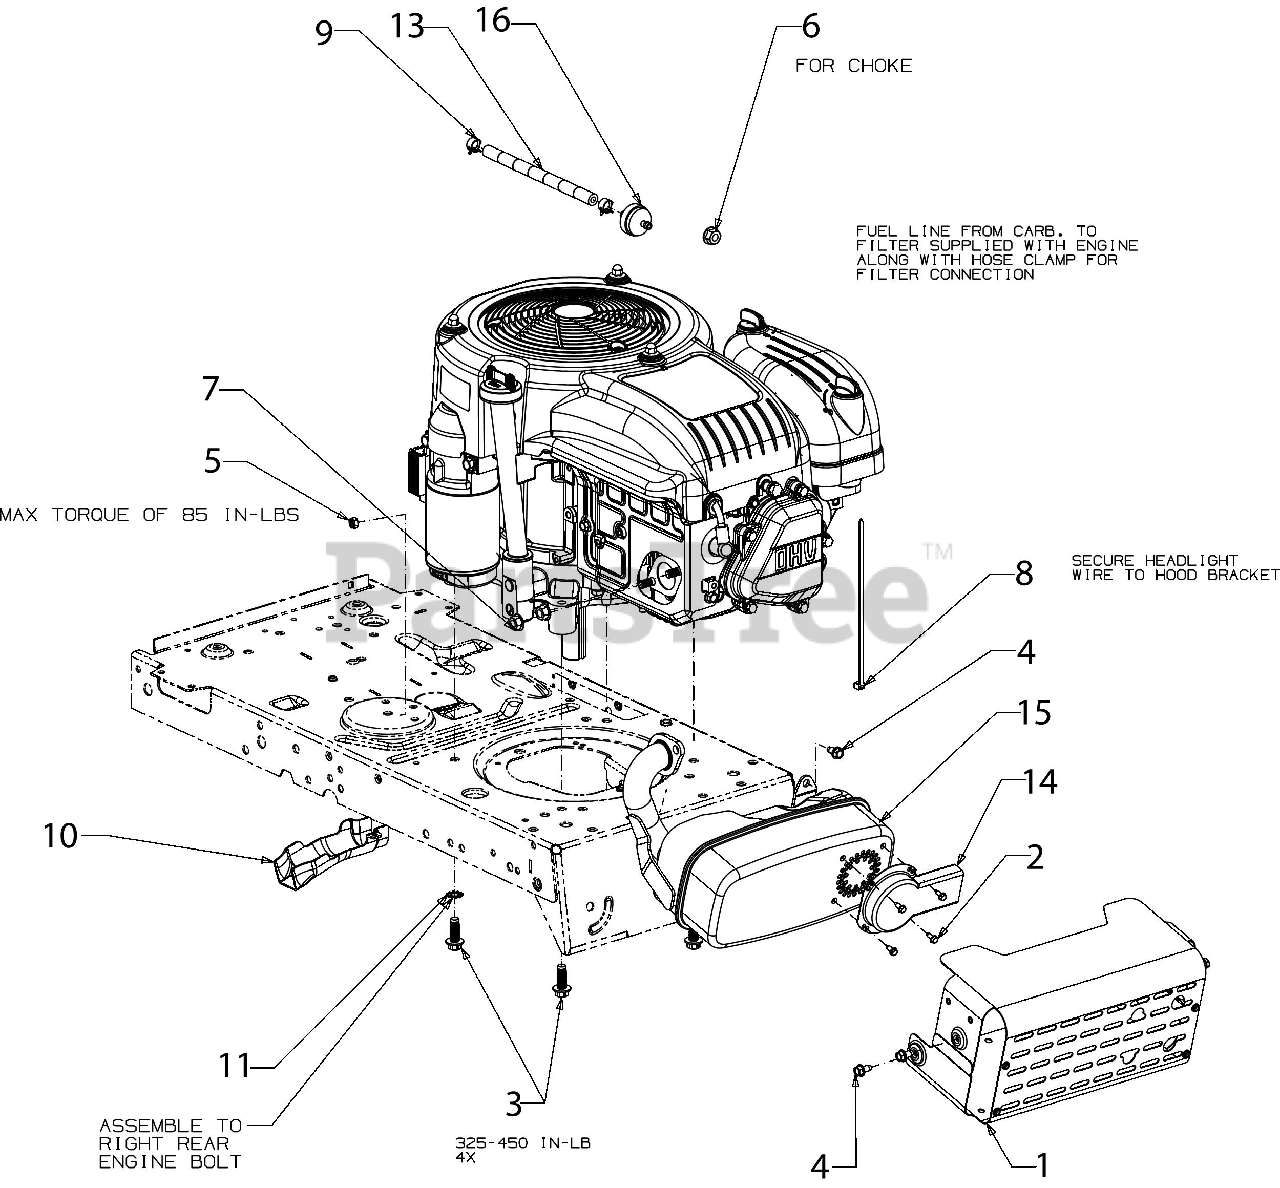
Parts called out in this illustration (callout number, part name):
2	HEX SCREW WASHER HD #8-18 x 0.500
3	SCREW 3/8-16 x 1
4	SCREW 1/4-20 X.500
5	HEX NUT
6	HEX FLANGE NUT
7	HEX FLANGE NUT M8X
8	7" CABLE TIE
9	HOSE CLAMP 1/20
10	OIL DRAIN SLEEVE
11	LOCK WASHER 3/8
13	FUEL HOSE LOW PERMEATION
14	EXHAUST DELECTOR
15	MUFFLER (SINGLE)
16	FUEL FILTER
